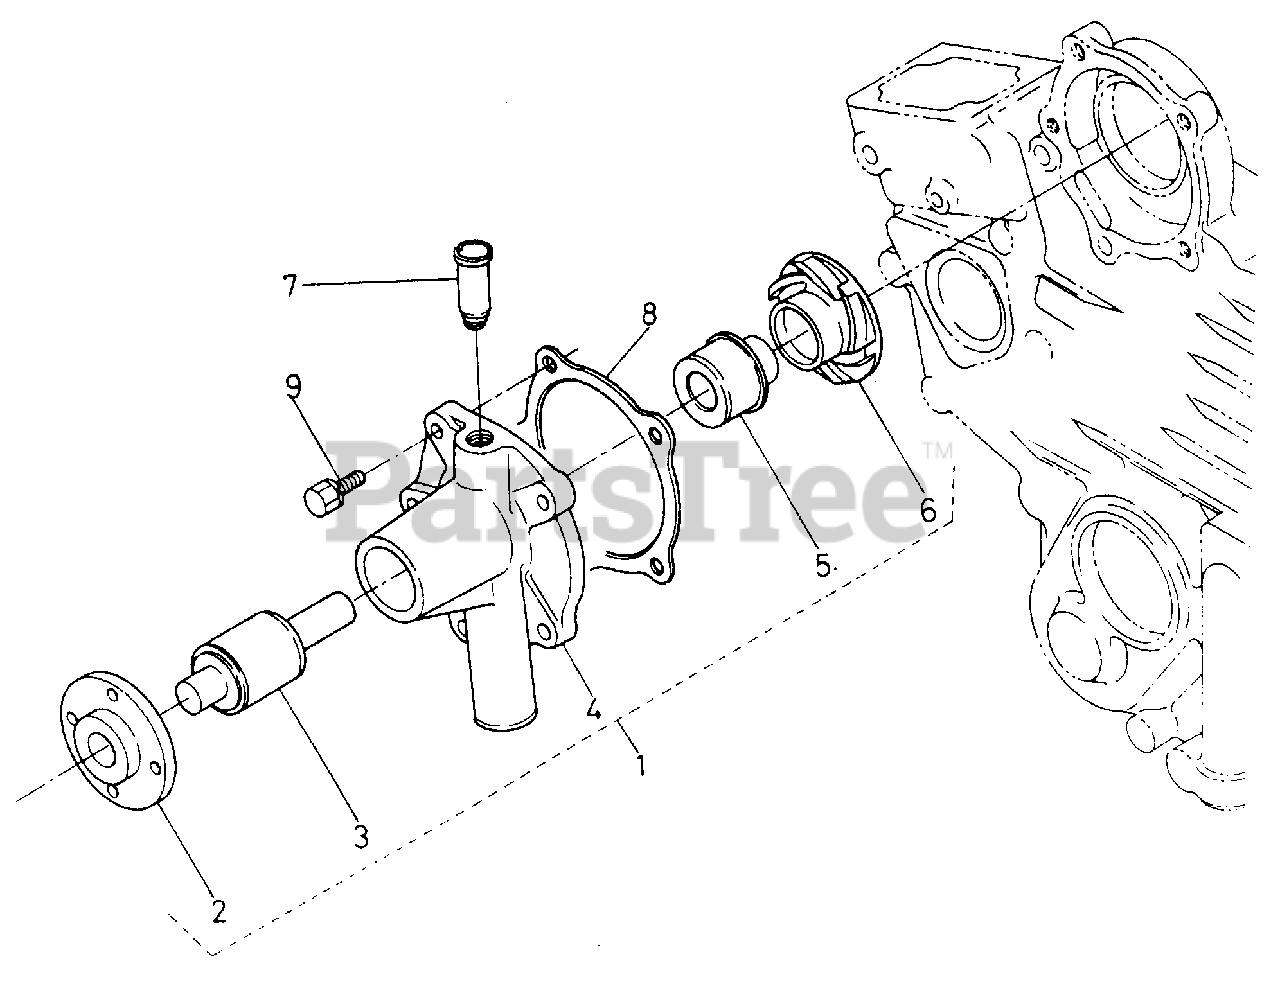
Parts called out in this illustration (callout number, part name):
1	Pump Assy, Water
2	Flange, Water Pump
6	Impeller, Water Pump
7	Pipe, Water Return 1
8	Gasket, Water Pump
9	Bolt, M6 X 25 Class 8.8
